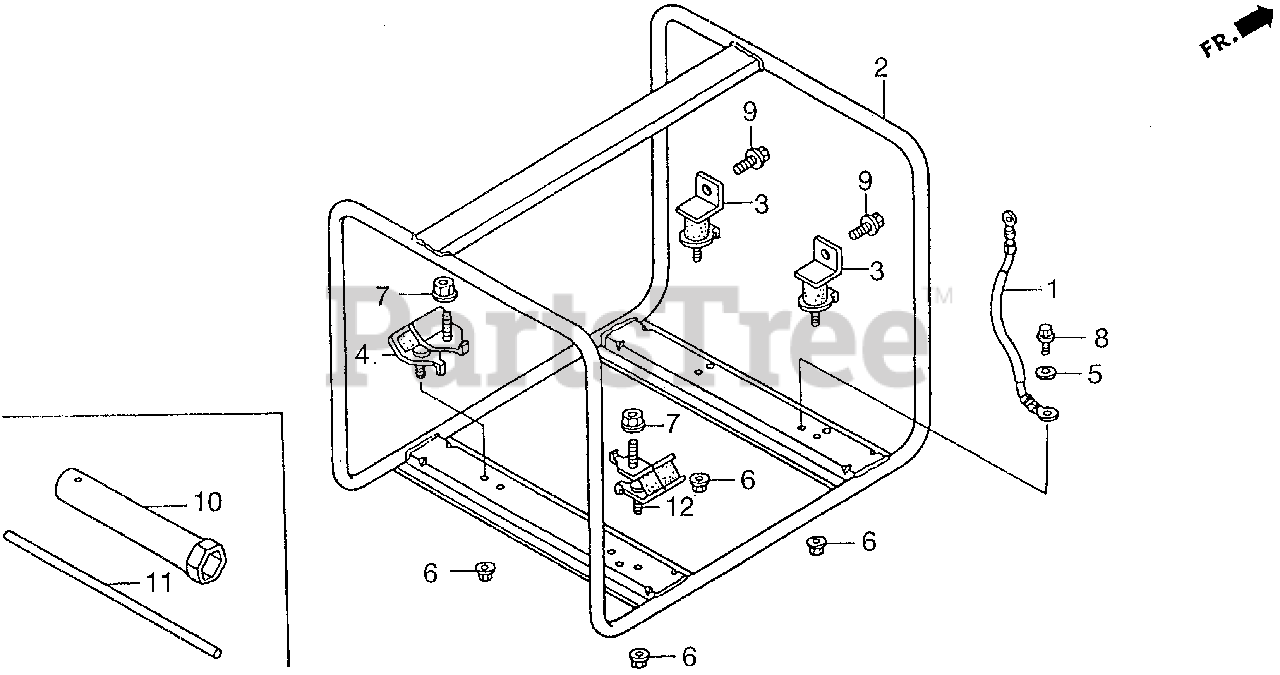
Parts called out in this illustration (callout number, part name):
1	CABLE, GROUND
2	FRAME *NH105* (MAT BLACK)
3	RUBBER, ALTERNATOR MOUNTING
4	RUBBER (LOWER)
5	WASHER, LOCK (6MM)
6	NUT, FLANGE (8MM)
7	NUT, FLANGE (10MM)
8	BOLT, FLANGE (6X10)
9	BOLT, FLANGE (8X20)
10	WRENCH, BOX (P21)
11	BAR A, HANDLE
12	RUBBER (LOWER)
